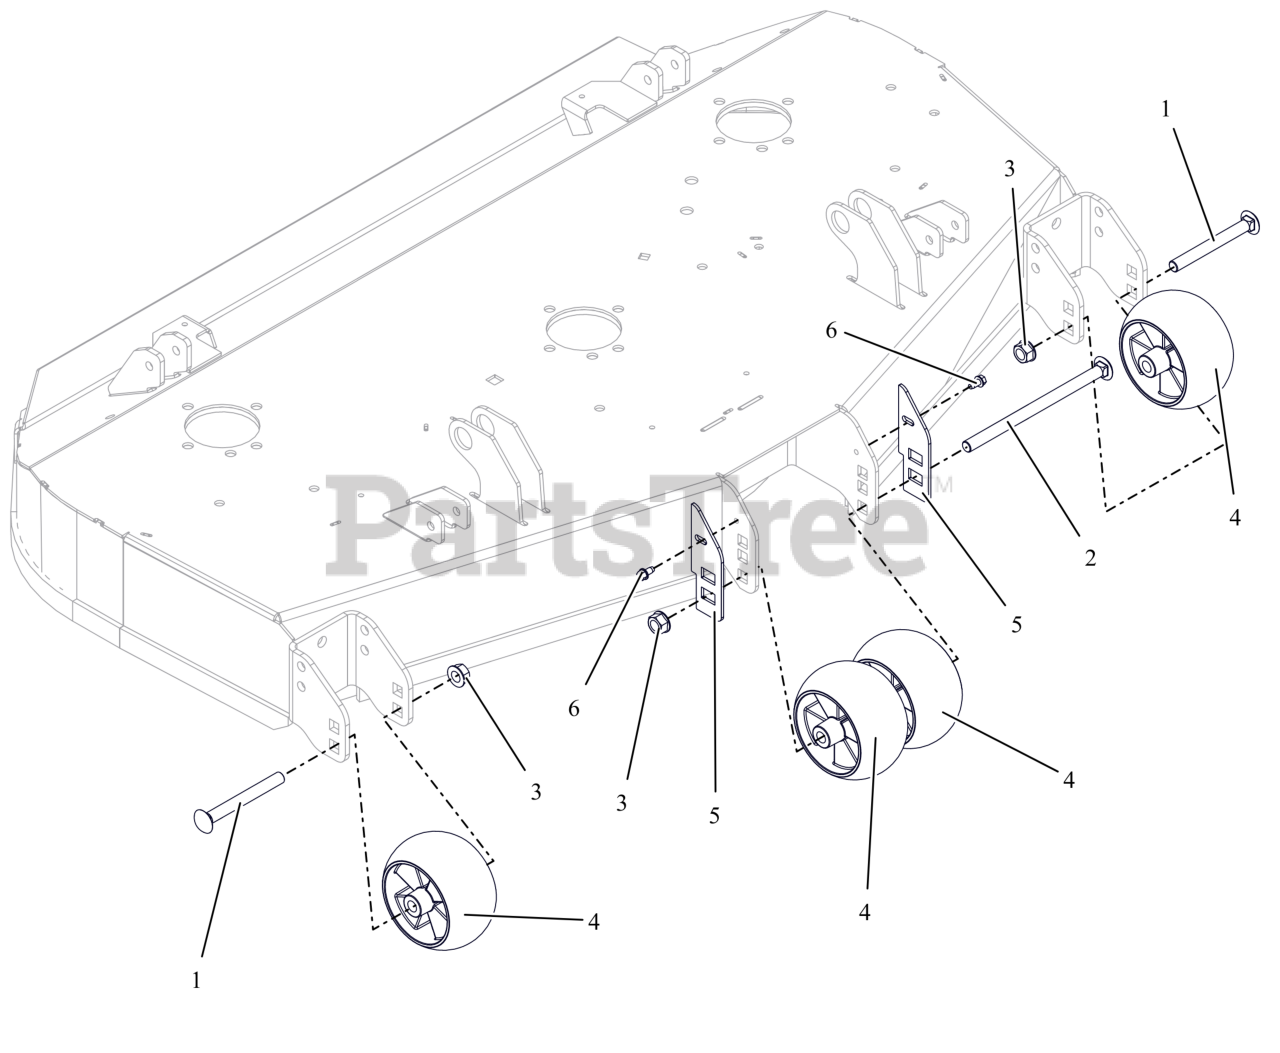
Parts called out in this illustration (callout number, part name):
1	BLT-RHNS .50-13X4.50 G5 ZCC NS
2	BLT-RHSN .50-13X8.00 G5 ZCC NS
3	NUT-LK-CTR-FLG .500-13 GG ZCC
4	WHEEL, ANTI SCALP - 5X3 CTR W/RIBS
5	PLATE, ANTI SCALP WHEEL 60" (ORANGE)
6	SCR-TAP .25-20X.50 HWH ZCC
